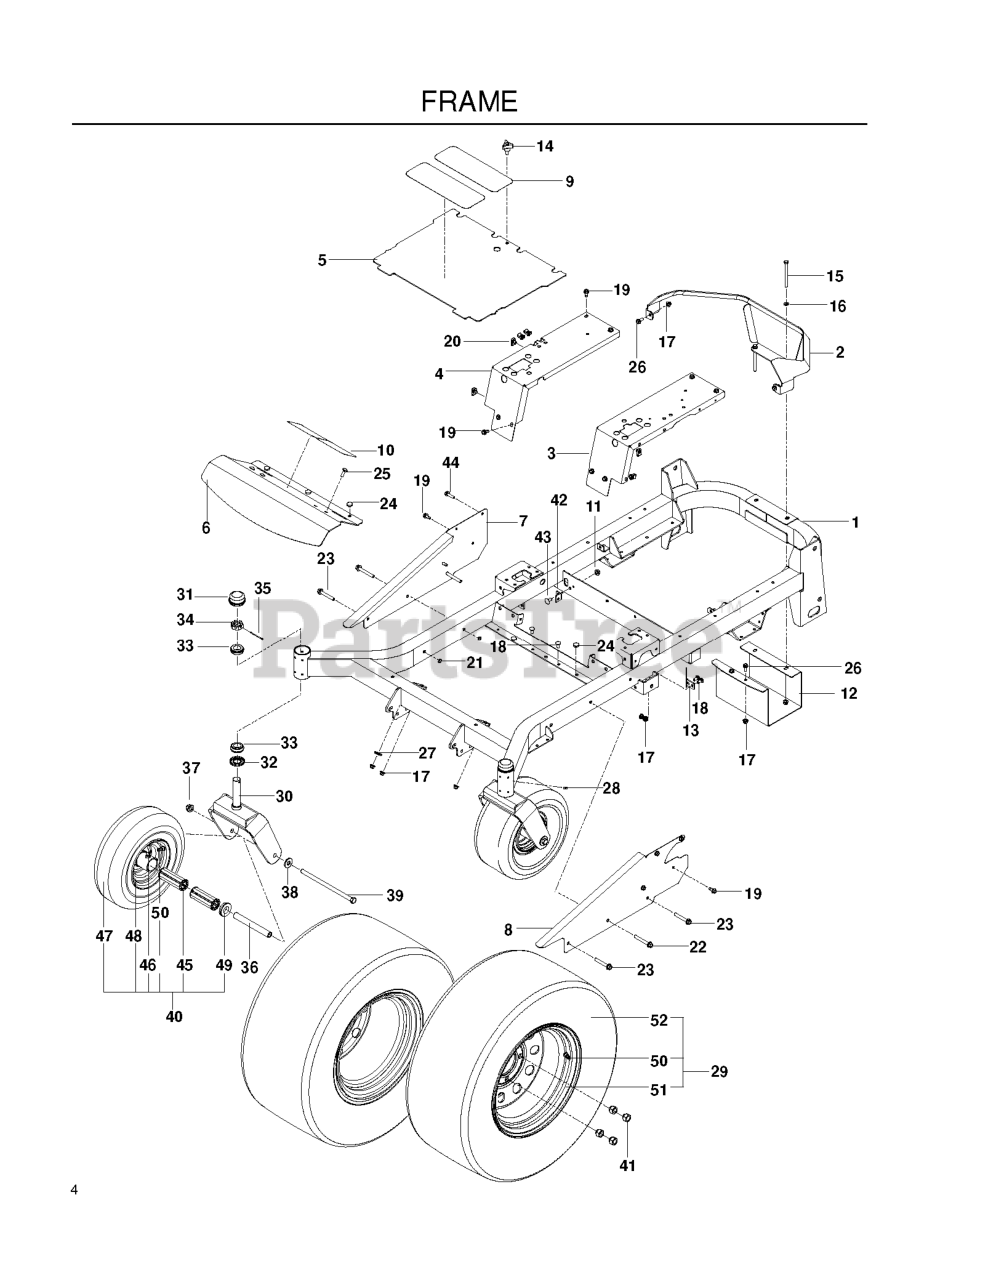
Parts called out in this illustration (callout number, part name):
1	FRAME W/DECALS
2	GUARD, REAR MZ, GRAY
3	PANEL, FILLER, LT
4	PANEL, FILLER RH ZT, ORG
5	PLATE, FLOOR W/DECALS
6	PLATE, FOOTREST
7	SIDE.RT.ORANGE
8	SIDE.LT.ORANGE
9	ANTI-SKID PAD
11	NUT 3/8-16 HEX FLG NYLOC ZD
12	SHIELD.MUFFLER.BLACK
13	STOP, DECK, EZ+
14	KNOB W/STUD
15	HCS 5/16C X 4
16	FLAT WASHER 5/16 SAE
17	5/16-18 NYLOC FLANGE NUT
18	BOLT 5/16C X 3/4" CARRIAGE
19	BOLT 5/16-18 X 3/4
20	U-CLIP 5/16-18 NUT RETAINER
21	NUT HEX 3/8-16 NYLON, THIN
22	HHFS 3/8-16 X 2 3/4
23	HHFS 3/8-16 X 2.5 GR 5 ZD
24	GROMMET, BUMPER
25	RHSNB 5/16C X 1
26	HHFS 5/16-18 X 3/4
27	WASHER 1/2" FLAT
29	RP WHEEL.ASM.23X10.5-12.TURFMA
30	YOKE.CASTER.ORANGE
31	GREASE CAP
33	TAPERED ROLLER BRG
34	NUT 1"C HEX SLOTTED
35	COTTER PIN 1/8 X 2
36	SPACER, PIVOT
37	NUT, 1/2-13 HEX FLG NYLOC ZD
38	WASH USS FLAT 1/2
39	HEX SCREW 1/2-13 X 9.5 GR5
40	TIRE.ASSEM.CASTER.13X6.5-6.SIL
41	LUG NUT 1/2F
42	BRACKET.DAMPENER.BLACK
43	RHSNB 3/8-16 X 3/4 GR 5 BLK ZN
44	HHFS 5/16-18 X 1.25 TPBLT GD 5
45	ROLLER BEARING-CAGED 3 1/4'
46	ZERK
47	TIRE.13X6.50-6.4.PLY
48	WHEEL.6X4.50.CASTER.SILVER
49	BEARING RETAINER
50	VALVE STEM TR-412
51	12"RIM 2.5" NEG OFFSET 8.5" W
52	TIRE.TURF.MASTER.23X10.5-12
